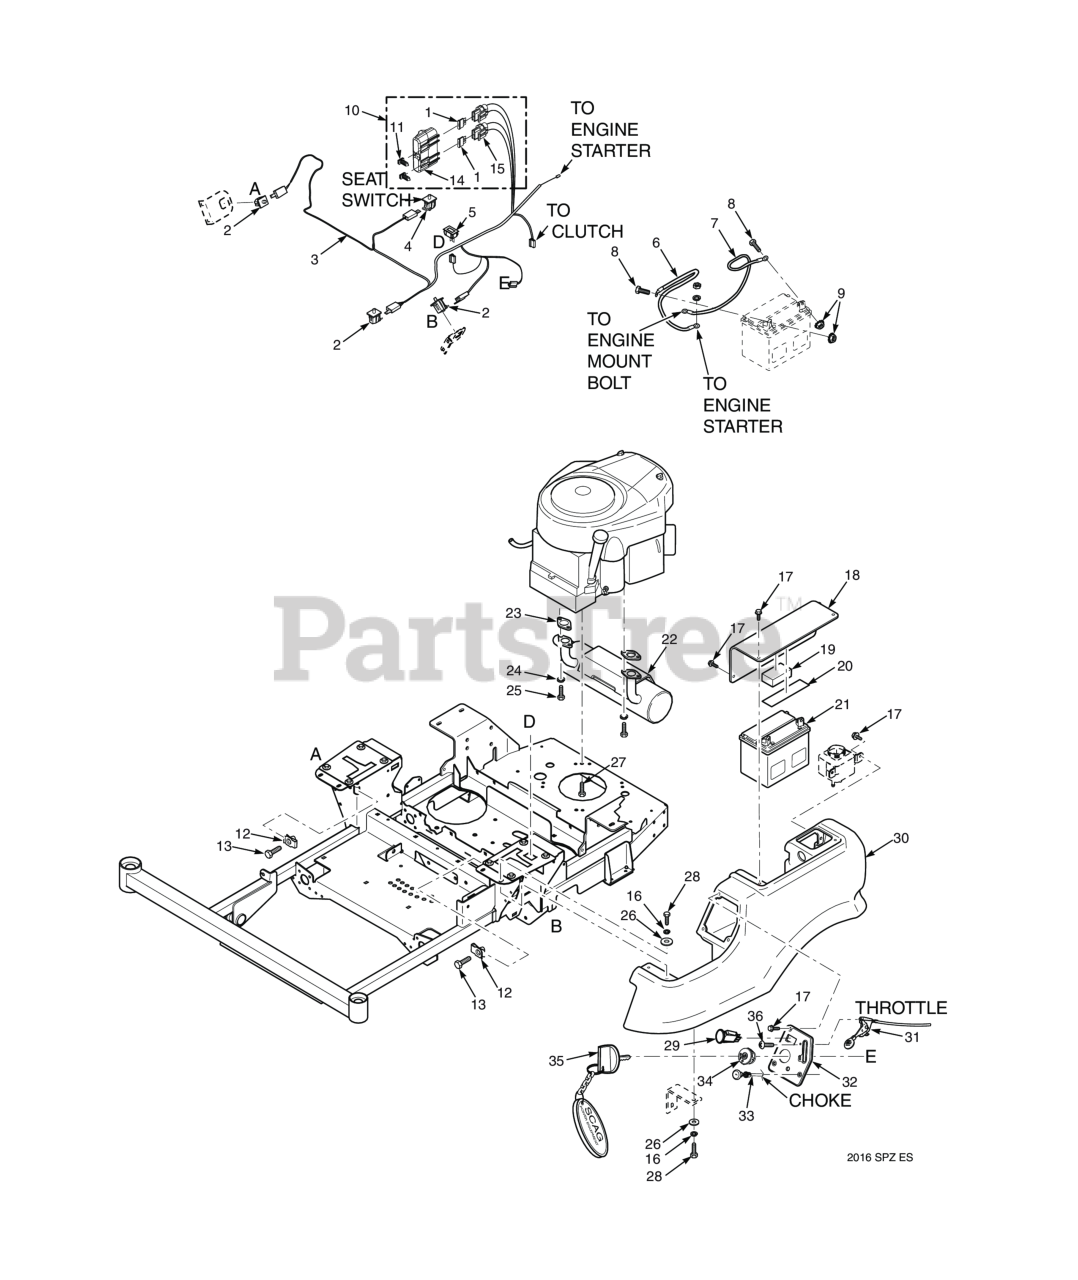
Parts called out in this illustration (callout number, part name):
1	FUSE, 20 AMP BLADE TYPE AUTOMOTIVE
2	Switch, Double Pole - Plunger
3	Wire Harness, Main
4	Switch, Double Pole - Twist
5	Hour Meter, Inductive
6	Battery Cable, 25" Red (Kawasaki)
7	Battery Cable, 27" Black (35BV & 37BV-EFI) - Briggs & Stratton
8	Bolt, Hex Head 1/4-20 x .5" Battery, (Not Available Through Scag)
9	Nut, 1/4 - 20 Hex
10	Double Fuse Assy.
11	Clip, Fuse Holder
12	U-Nut, 3/8-16 (short)
13	Bolt, Hex Head 3/8-16 x 1-1/4" with Thread Lock Patch
14	Cover, Sealed Double
15	Fuse Holder Assembly
16	Lockwasher, 5/16 (.317 x .586 x .078) Helical Spring
17	CAP SCREW, 1/4-20 X 1/2" SERRATED FLANGE HEX
18	Battery Cover
19	Pad, Battery - Rubber
20	Rubber Pad
21	Battery, 350 CCA (not available through Scag)
22	Muffler, Kawasaki FS/FX
22	Muffler, Kohler
23	Exhaust Gasket
24	Lockwasher
25	Bolt
26	Flatwasher, 5/16-.375 x .875 x .083 (35BV & 37BV-EFI)
27	Bolt, Hex Head Self-Tap 3/8-16 x 1-1/4" (Kohler x3 - 25EFI, Kohler x4 - 29EFI)
27	Bolt, Hex Head 3/8-16 x 1-1/4", Kawasaki FX / FS
27	Lockwasher, 3/8" Spring, Kawasaki FX / FS
28	BOLT, SERRATED FLANGE HEX HEAD 5/16-18 X 3/4"
29	Switch, PTO - 10 Amp
30	Tank, LH - SPZ
31	Throttle Cable, Briggs & Stratton
32	INSTR PANEL W/ DECAL, SFZ
33	Choke Cable, Briggs & Stratton
33	Choke Control, Kawasaki
34	Ignition Switch
35	Key w/Shroud Only
35	Key, Assembly w/Fob
36	Bolt, Carriage #10-24 x 1/2"
